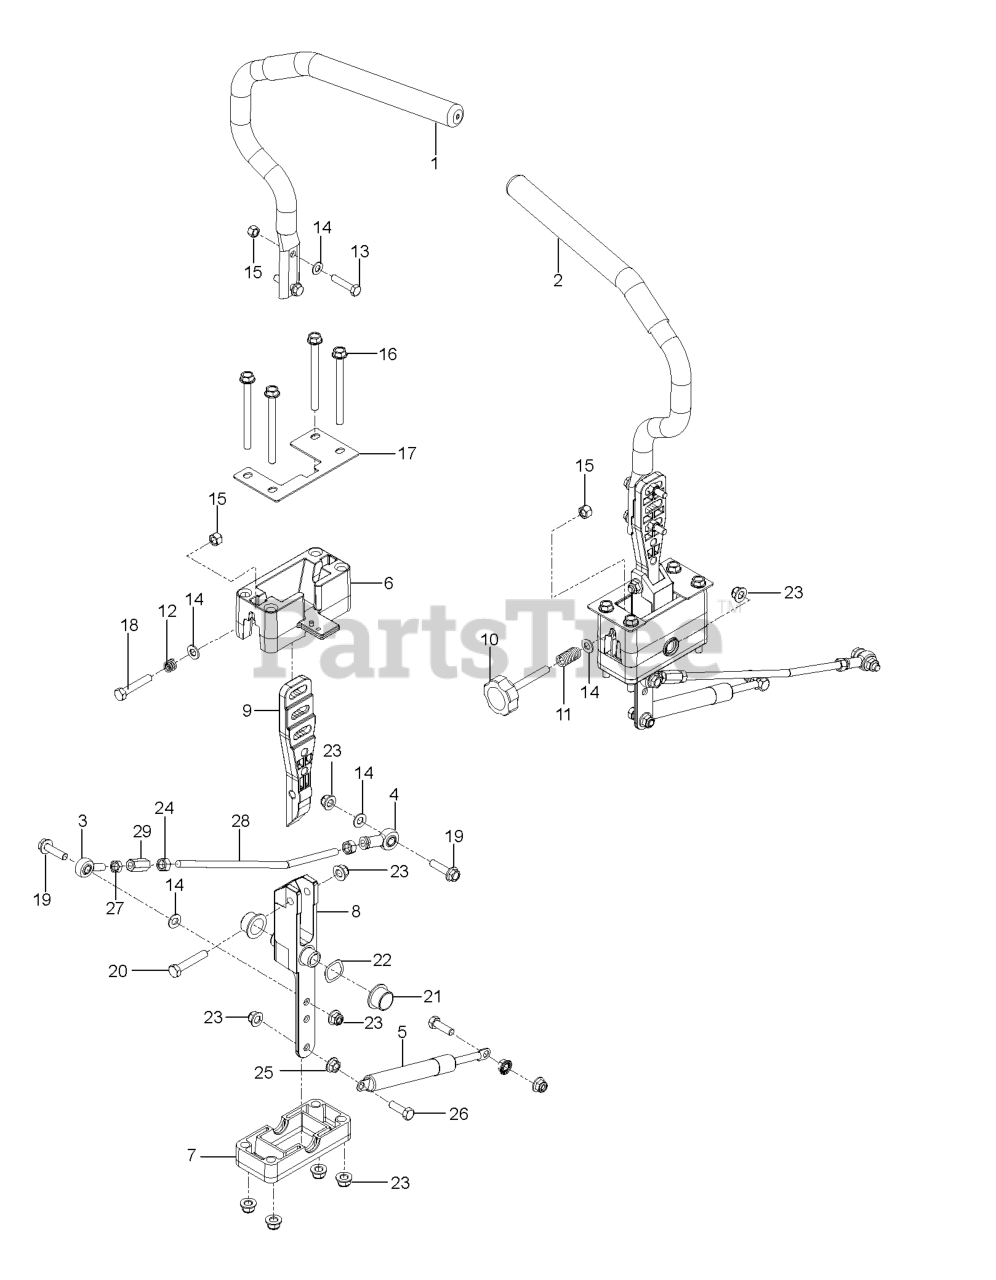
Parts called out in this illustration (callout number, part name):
1	LEVER.DRIVE.W/GRIP.RIGHT
2	LEVER.DRIVE.W/GRIP.LEFT
3	RP.ROD.END.LH
4	RH ROD END
6	BLOCK, UPPER
7	BLOCK, LOWER
8	PIVOT.SECTION.DRIVE.CONTROL
9	MOUNT, DR CNTRL HANDLE
13	CAPSCREW 5/16 X 1/1/2 HEX HEAD
14	FLAT WASHER 5/16 SAE
15	NUT 5/16 NYLOC
16	HHFS 5/16-18 X 3 3/4
17	PLATE, NEUTRAL STOP, BLACK
18	HCS 5/16-18X1-3/4 TPBLT
19	HHFS 5/16-18 X 1.25 TPBLT GD 5
20	HCS 5/16C X 1 3/4
21	BEARING, FLANGE
22	WASHER, .825 X 1.087, WAVE
23	5/16-18 NYLOC FLANGE NUT
25	NUT 5/16C WHIZ
26	HCS 5/16C X 1
27	NUT 5/16F LEFTHAND
28	ROD, CONTROL
29	ROD END COUPLER
